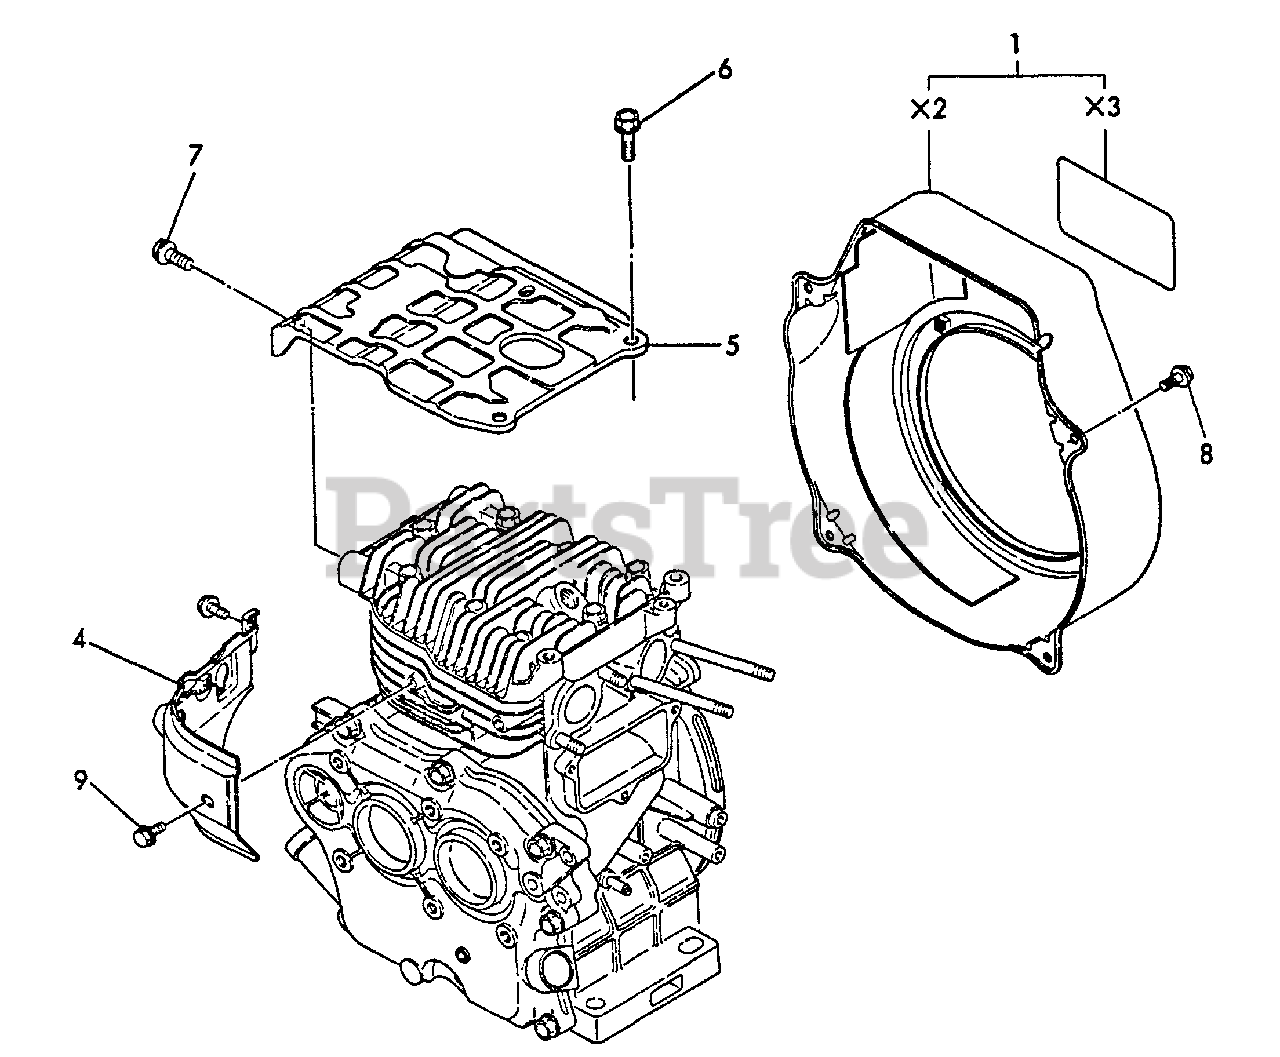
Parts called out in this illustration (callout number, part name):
1	COVER, FAN
4	SHIELD, CYLINDER
5	COVER, HEAD
6	BOLT - 8×14 -- PLATED
7	BOLT - 8×20 -- PLATED
8	BOLT - 6×8 -- PLATED
9	BOLT - 6×8 -- PLATED
